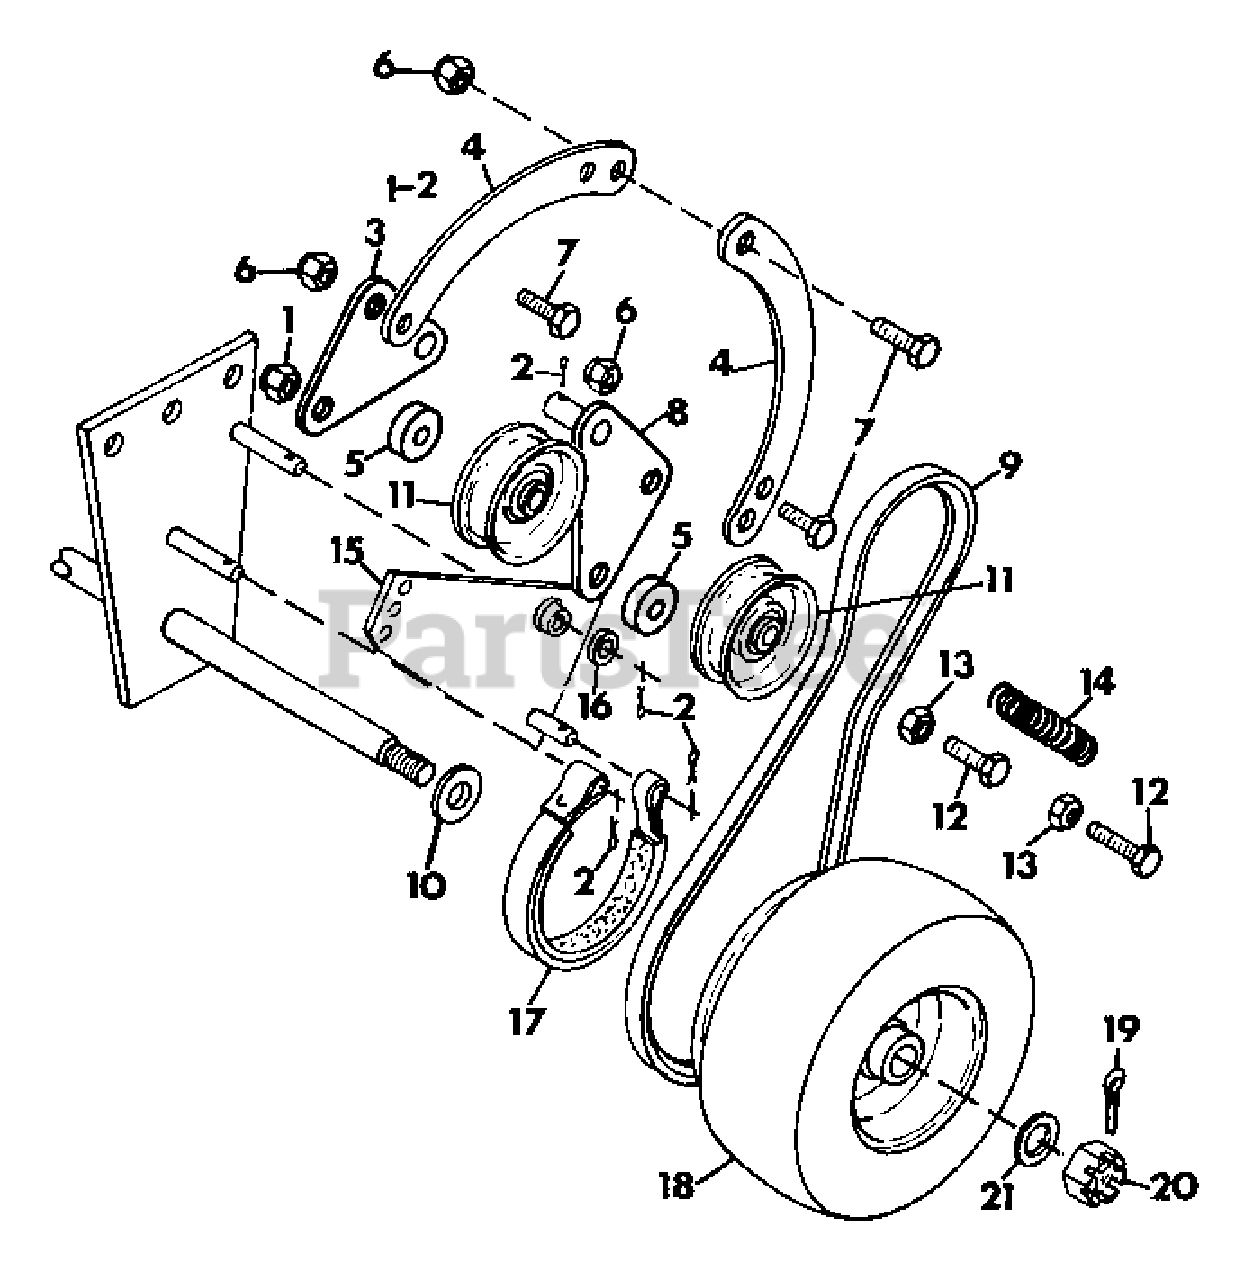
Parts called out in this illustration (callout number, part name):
1	Nut, Lock 3/8-16
2	Pin, Cotter .09x.75
3	Weldment, Wheel Clutch L.H.
4	Strap, Wheel Clutch Actuating
5	Spacer, Idler
6	Nut, Lock 5/16-18
7	Bolt, Hex 5/16-18x.625
8	Lever, Wheel Clutch R.H.
9	Belt, Traction
10	Spacer, Wheel
11	Sheave, Idler
12	Bolt, Hex 3/8-16x2.0
13	Nut, Hex 3/8-16
14	spring
15	Weldment, Brake Lever L.H.
15	Weldment, Brake Lever R.H.
16	Washer, Flat .344x.688x.065
17	Assembly, Brake Band L.H.
17	Assembly, Brake Band R.H.
18	Assembly, Wheel and Tire
19	Pin, Cotter .156x1.50
20	Nut, Slotted 3/4-16
21	Race, Bearing Thrust
